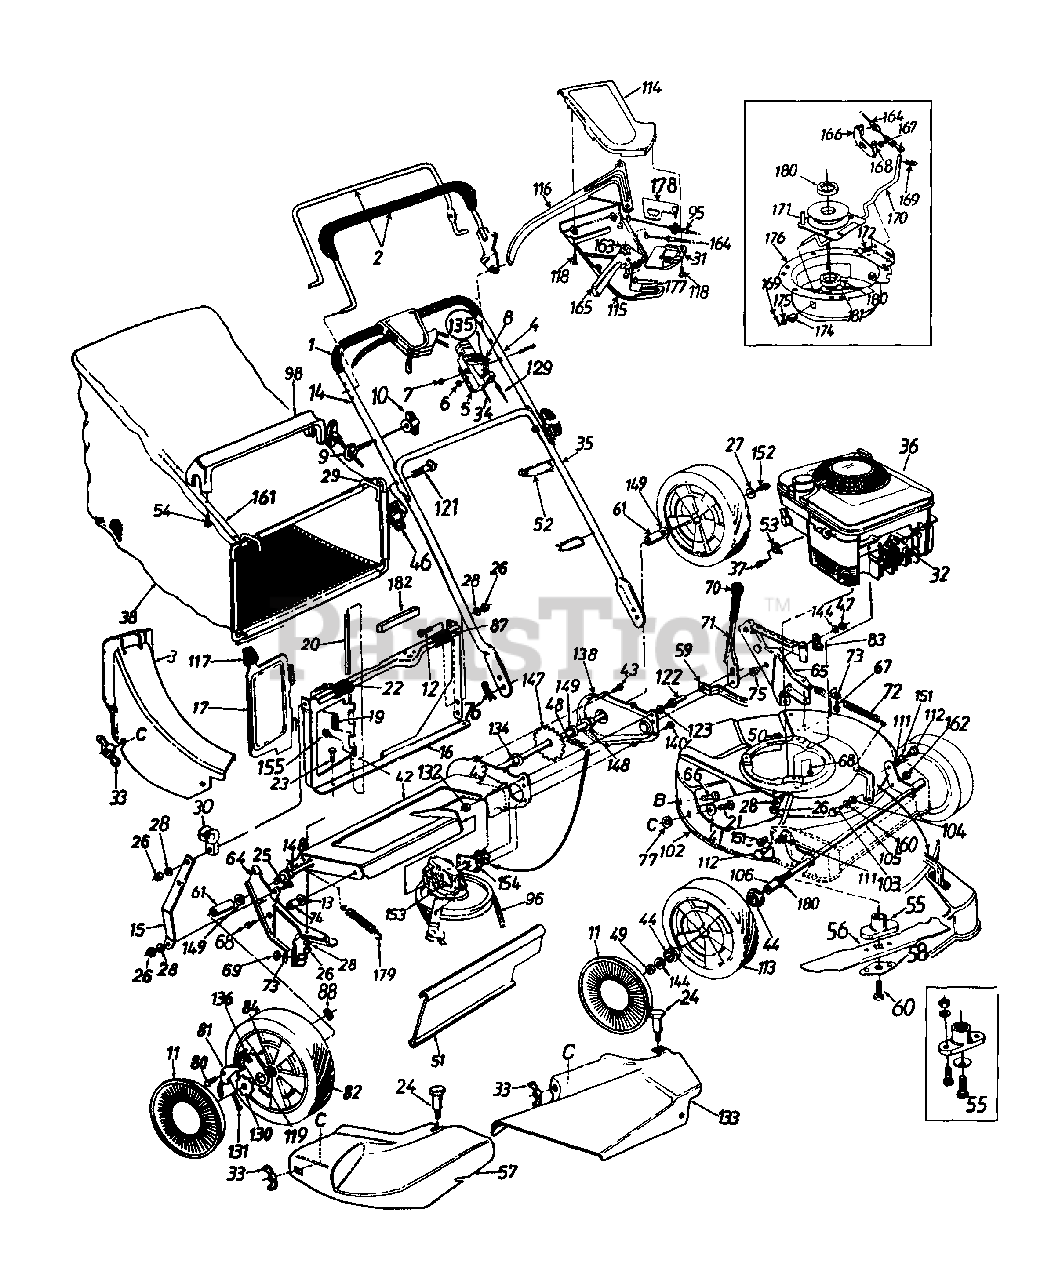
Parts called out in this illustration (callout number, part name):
1	Foam Grip
3	Rear Discharge Chute Ass'y.
4	Oval C-Sunk Scr.
5	Throttle Body
6	Spr. Wash. .66" I.D.
7	Hex L-Nut 1/4-20 Thd.
8	Throttle Lever
9	Rope Guide
10	Handle Knob 1/4-20 Thd.
11	Hub Cap
12	Truss Mach. Scr. 1/4-20 x .62" Lg.
13	Fl-Wash. .383" I.D. x 1" O.D.
20	Pivot Pin
21	Carriage Bolt 1/4-20 x .62"
22	Truss Mach. Scr. 1/4-20 x 3/4" Lg.
23	Hex AB-Tap Scr. 1/4 x .38" Lg.
24	Shoulder Bolt .312 Dia. x .18 Lg. - Special
25	Hex Bolt 1/4-20 x .62" Lg.
26	Hex Nut 1/4-20 Thd.
27	Bell-Wash. 1/4" I.D.
28	L-Wash. 1/4" I.D.
30	Rope Guide
31	S.P. Control Cover
32	Spark Plug Insulator
33	Wing Nut w/Washer
34	Throttle Control Wire 61"
36	Engine
37	Hex Self-Tap Scr. #10-32 x .62" Lg.
38	Grass Bag (Plain)
41	Fl-Wash. .344" I.D. x .62"
44	Ball Bearing
46	Hand Knob
47	Hex Patch L-Nut 3/8-24 Thd.
48	#48 Chain .500" Pitch x 30 Links
49	Hex L-Nut 1/2-20 Thd.
51	Rear Flap 4.8" x 18" Lg.
52	Cable Tie
53	Cable Clamp
54	Hex AB Scr. #12 x 1.25" Lg.
55	Blade Adapter
56	21" Mulching Blade
57	Mulching Plug
58	Blade Belt Support
59	Height Adj. Connecting Arm
60	Hex Bolt 3/8-24 x 1.5" Lg.
61	Spacer .513" I.D. x .703" O.D. x .69" Lg.
67	Hex Wash. Hd. B-Tap Scr. 5/16-18
68	Hex Wash. Hd. TT-Tap Scr. 3/8-16
69	Hex Nut 5/16-18 Thd.
71	Height Adj. Lever
72	Extension Spring .75" O.D. x 8" Lg.
73	Bell-Wash. 5/16" I.D.
74	Spacer
75	Shld. Spacer .500" Dia.
76	Hairpin Clip
77	Bolt Retainer 1/4 x .50" O.D.
80	Shld. Scr. .342" Dia. x .268
81	Pawl - R.H.
82	Rear Wheel Ass'y. Comp
83	Clamp
84	Bearing 1/2" I.D.
87	Panel Clip
88	Weld L-Nut 1/4-20 Thd.
95	S.P. Cable
96	"V"-Belt
98	Bag Handle
104	Bell-Wash. .515" I.D. x 1.0" O.D.
111	Intern. L-Wash. 3/8 I.D.
112	Shld. Bolt .575" Dia. x .42
113	Front Wheel Ass'y. Comp.
114	Self-Propelled Control Cover
115	Self-Propelled Control Cover
116	Control Lever
117	Door Grip
118	Fl-"C"-Sunk Hd. Tap Scr. #10 x .75" Lg.
119	Pawl Plate
121	Curved Hd. Bolt 5/16-18 x 2" Lg.
122	Shld. Pin 3/8-24 x 1.43" Lg.
123	L-Wash. 3/8" I.D.
129	Control Cable 43" Lg.
130	Ratchet Wheel 1.62" O.D.
131	Cotter Pin 1/8" Dia. x 1.00" Lg.
132	Hex Jam Nut 3/8-24 Thd.
133	Side Chute Deflector Ass'y.
134	Hex Flange Bearing
135	Throttle Box Comp.
136	Spring - Nylon
144	Fl-Wash. .385" I.D. x .87"
147	Rear Shaft Ass'y. 21.94" Lg.
148	Hex Flange Bearing .506" I.D. Plastic
149	Fl-Wash. .531" I.D. x .930"
151	Flanged Nyliner Brg.
152	Hex Bolt 1/4-20 x .62" Lg. (Grade 5)
153	Transmission Comp. (See Breakdown)
154	Hex Bearing Cup
155	Hex B-Tap Scr. #10 x .38
160	Fl-Wash. .51" I.D. x .75" O.D.
162	Hex Jam Nut 3/8-16 Thd.
163	3-Tooth Rack Gear Insert
164	Spd. Control Cable - 50" Lg.
165	6-Spd. Shift Lever
168	Hex Cent. L-Nut 1/4-20 Thd.
169	Cot.-Pin 3/32" Dia. x .75" Lg.
170	Shift Rod
171	Pulley Ass'y.
172	Carr. Bolt 1/4-20 x .50" Lg.
174	Flanged Bushing
175	Fl-Wash. .328" I.D. x .68" O.D.
178	6-Speed Rack Cable Brkt.
179	Ext. Spring 3.8" Lg.
180	Spacer .885" I.D. x 1" O.D.
181	Wave Wash. .88" I.D. x 1.38" O.D.
182	Foam Strip
